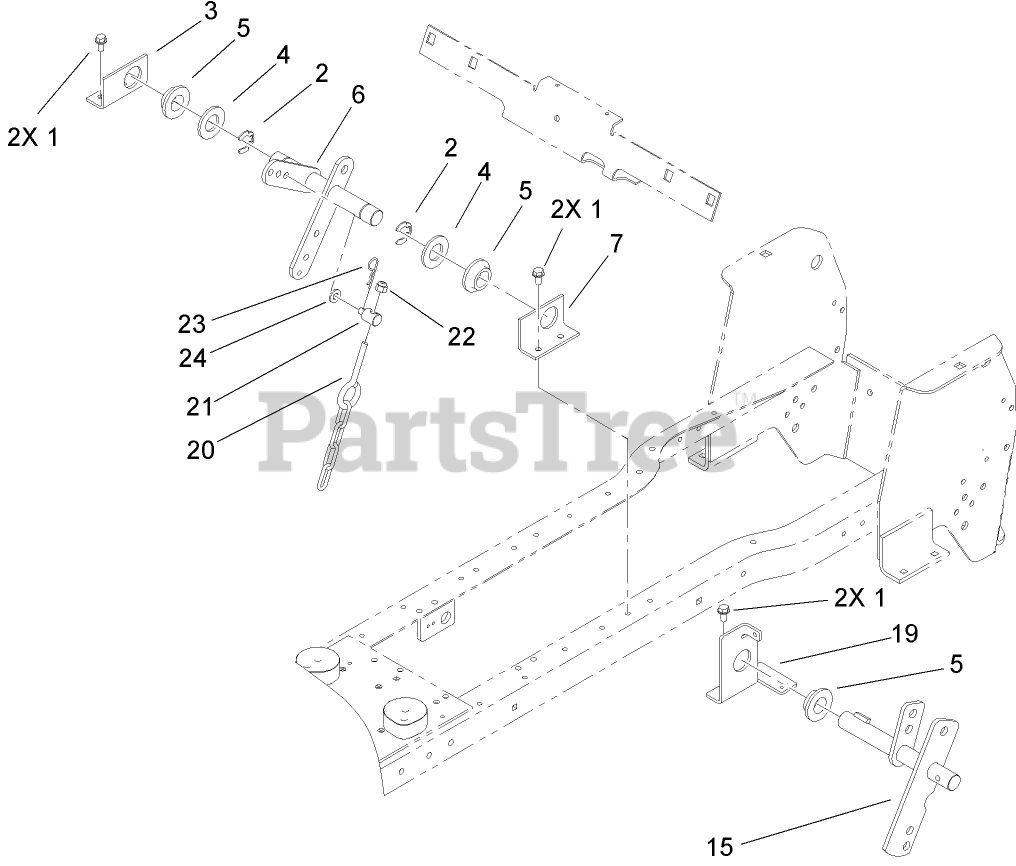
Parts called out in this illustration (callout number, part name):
1	SCREW-HWHTF
2	RING-RETAINING
3	BRACKET-PIVOT LINKAGE, RH
4	WASHER-FLAT
5	BEARING-FLANGE
6	LIFT LEVER ASM
7	BRACKET-PIVOT LINKAGE, LH
15	LIFT ARM ASM
19	BRACKET-PIVOT, LIFT
20	CHAIN-LIFT
21	TRUNNION
22	NUT-LOCK, NI
23	PIN-HAIR
24	WASHER-FLAT
